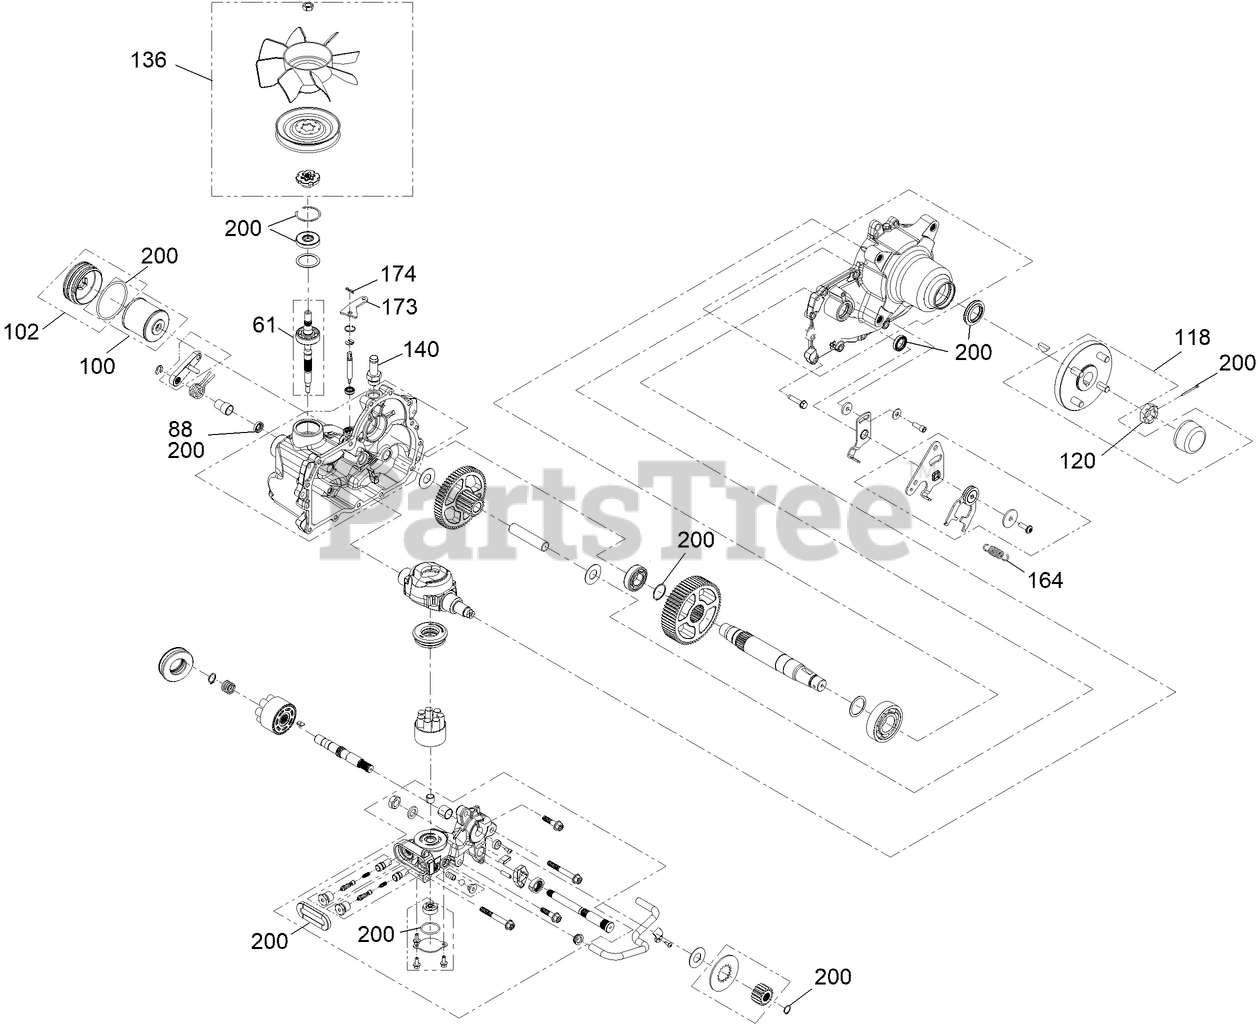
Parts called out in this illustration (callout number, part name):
61	Kit, Input Shaft
88	Seal, Brake
100	Kit, Filter
102	Kit, Filler Cap
118	HUB-4 BOLT
120	NUT, SLOTTED
136	KIT, FAN AND PULLEY
140	Fitting-5/8 Beaded, 7/8 SAE
164	SPRING-EXTENSION
173	Plate-Lever, Bypass
174	PIN-COTTER, LOCKING
200	Kit-Seal
